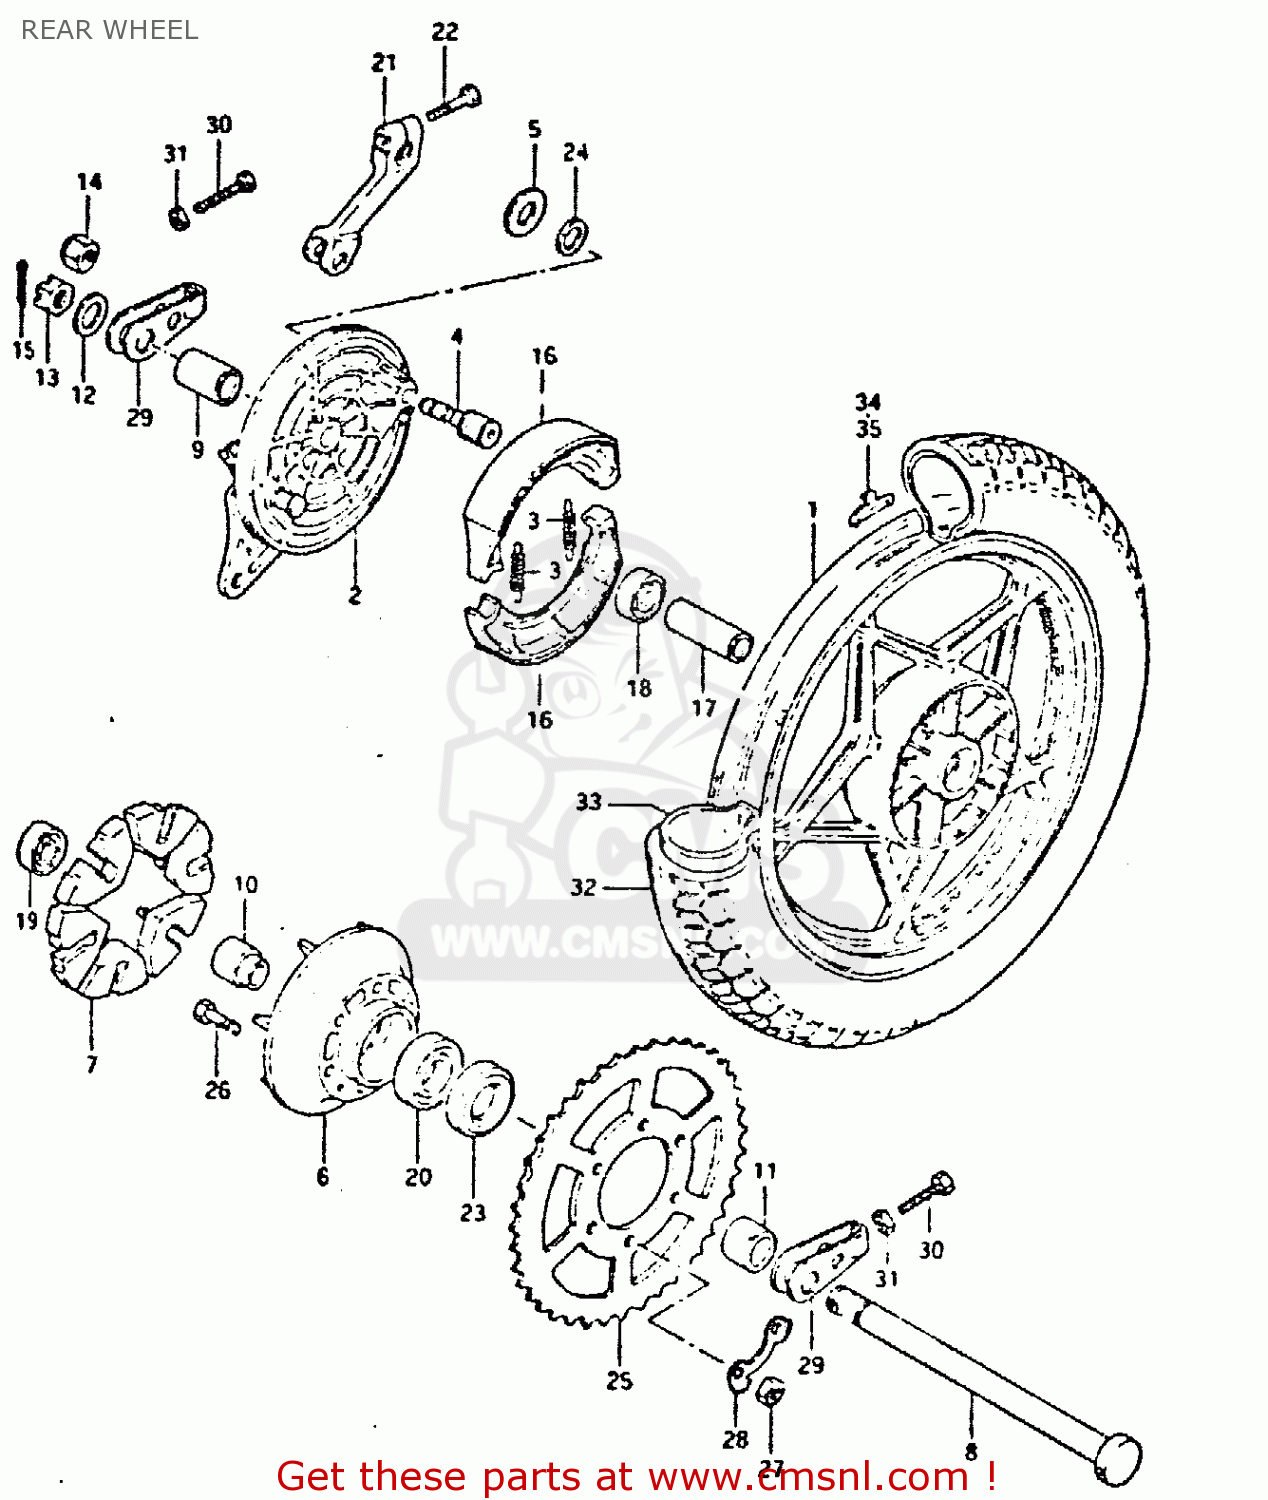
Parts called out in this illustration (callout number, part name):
1	WHEEL,REAR
2	PANEL,REAR HUB
3	SPRING,BRAKE SHOE
4	CAM,FRONT BRAKE
5	WASHER (15X24X1.6)
6	DRUM,REAR SPROCKET MOUNT
7	ABSORBER,RR HUB SHOCK
8	AXLE,REAR
9	SPACER(17.5X28X44.8)
10	SPACER,REAR HUB BEARING
11	SPACER(17X30.5X22.3)
12	WASHER (17X30X3.2)
13	NUT
15	PIN,COTTER
16	SHOE,BRAKE
17	SPACER (17.6X24X57)
18	BEARING
19	BEARING
20	BEARING
21	LEVER,RR BRAKE CAM
22	BOLT
23	SEAL,OIL(30.5X52X8)
24	O-RING,BOSS
25	SPROCKET,REAR (NT:44)
26	BOLT
27	NUT
28	WASHER
29	ADJUSTER,CHAIN
30	BOLT
31	NUT
32	TIRE
33	TUBE ASSEMBLY,WHEEL,INNER
34	BALANCER, NO. 1
35	BALANCER,WHEEL
